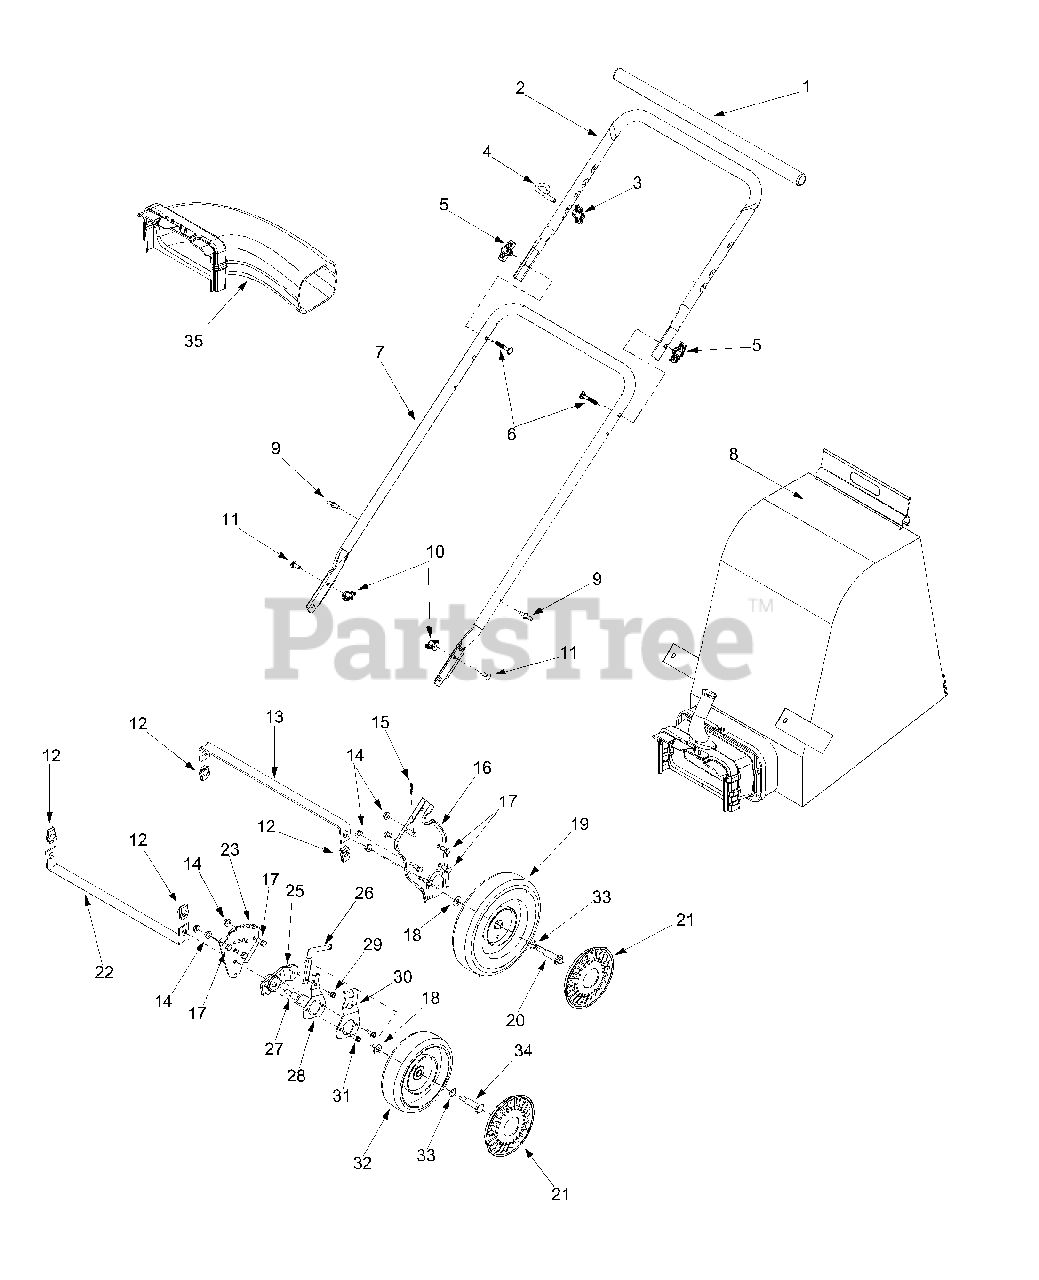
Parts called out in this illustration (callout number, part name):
1	Foam Grip
4	Eye Bolt
5	Handle Knob 5/16-18
6	Carriage Bolt
8	Bag Ass'y
9	Studs
10	Wing Nut 1/4-20
11	Carriage Screw 1/4-20 x .75
12	Lock U-Clip Nut 3/8-16
15	Cotter Pin
17	Hex Cap Screw 5/16-18 x .625
18	Bell Washer .401 ID x .870 OD
19	Wheel 9 x 2
20	Shoulder Screw 3/8-16
21	Hubcap
26	Handle Height Adjuster
27	Shoulder Screw 3/8-16
28	Height Adjuster Plate Spring
29	Hex Washer Screw 1/4-20 x .375
32	Wheel 8 x 2
33	Wave Washer .531 ID x .781 OD
34	Shoulder Screw
35	Blower Chute Assembly
